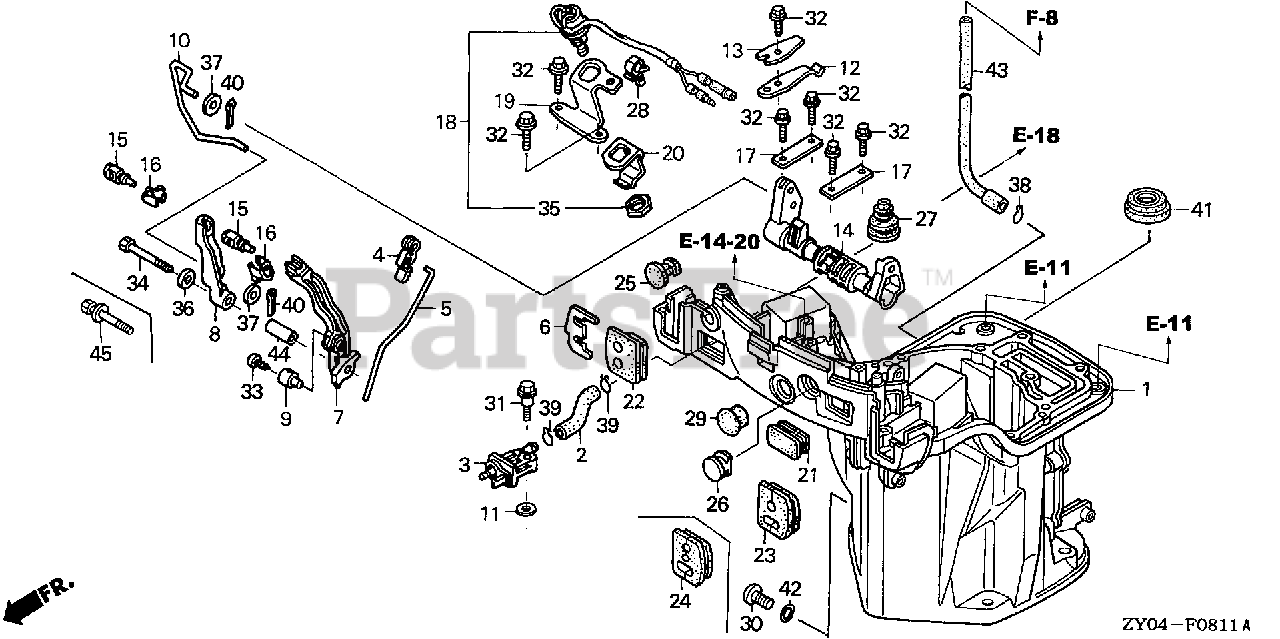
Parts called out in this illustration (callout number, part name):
2	TUBE A, FUEL
3	CONNECTOR ASSY., FUEL (B)
4	LINKAGE, PIVOT
5	ROD, THROTTLE
6	PLATE, REMOTE CONTROL CABLE
7	ARM, THROTTLE REMOTE
8	ARM, SHIFT LINK
9	HOLDER, THROTTLE ROD
10	ROD, SHIFT LINK
11	WASHER, PIVOT
12	SPRING, CLICK
13	SPRING, CLICK ASSIST
14	SHAFT, SHIFT
15	PIVOT, SHIFT
16	PLATE, LOCK
17	PLATE, SHIFT SHAFT
18	SWITCH ASSY., NEUTRAL
19	BRACKET, NEUTRAL SWITCH
20	PLATE, NEUTRAL SWITCH
21	GROMMET G, OIL CASE
22	GROMMET A, OIL CASE
24	GROMMET B, OIL CASE (PT)
25	GROMMET F, OIL CASE
26	GROMMET D, OIL CASE
27	GROMMET E, OIL CASE
28	CLIP, BRAKE PIPE (A)
29	CAP, HANDLE (LOWER)
30	BOLT, OIL CHECK
31	BOLT, SPECIAL (6X22) (CT200)
32	BOLT, FLANGE (5X12) (CT200)
33	BOLT, RECESSED (5X8)
35	NUT, HEX. (20MM)
37	WASHER, PLAIN (7MM)
38	CLIP, TUBE (B10)
39	CLIP, TUBE (B12)
40	PIN, SPLIT (2.0)
41	SEAL, WATER (15X28X6)
42	O-RING (5.5X1.5)
43	TUBE, WATER CHECK
44	COLLAR, DISTANCE (6X11X27)
45	BOLT-WASHER (6X40)
